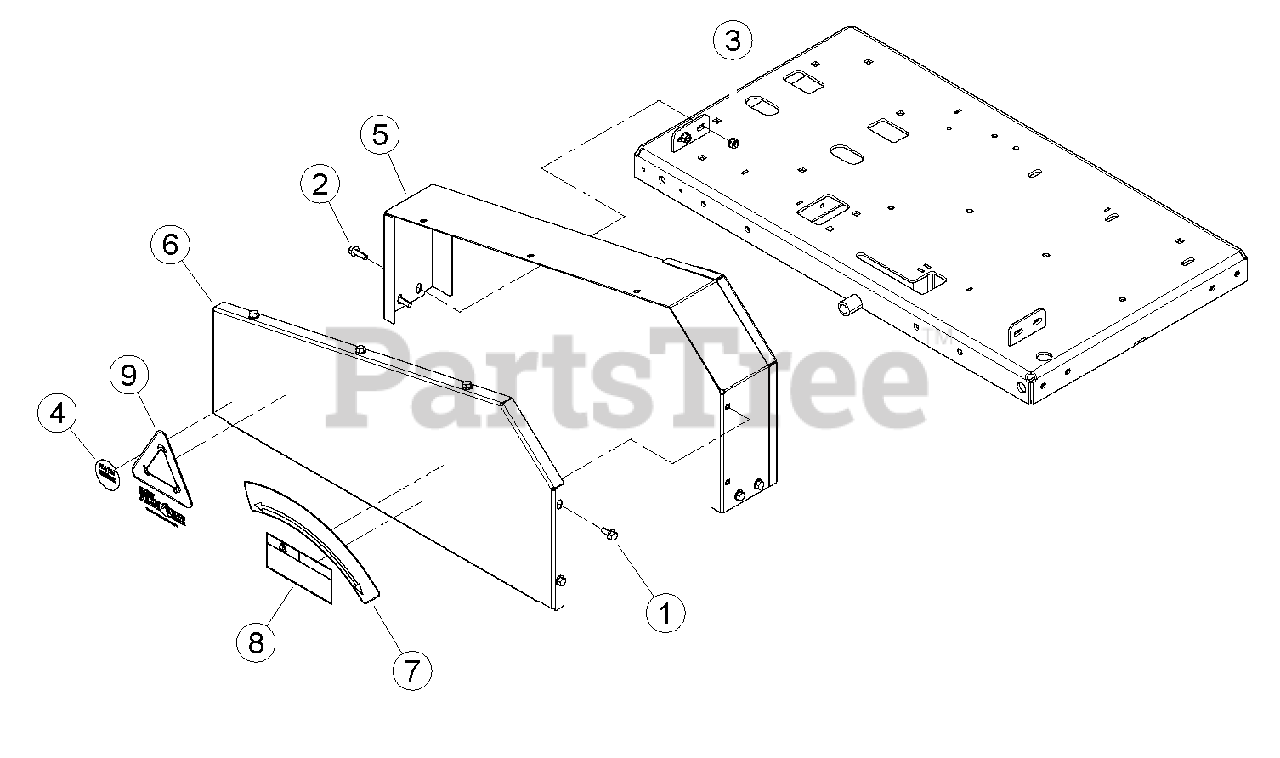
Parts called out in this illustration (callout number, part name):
1	BOLT, 5/16 X 3/4 FLANGE NC
2	BOLT, 5/16 X 1 FLANGE NC
3	NUT, 5/16-18 NYLOCK-FLANGE
4	DECAL, NATM COMPLIANCE
5	WELDMENT, SHIELD
6	SHIELD, CH4400 BELT SERVICE PART
7	DECAL, START/ENGAGE
8	DECAL, MUTILINGUAL MANUAL
9	LOGO, CHIP IT (WHITE)
